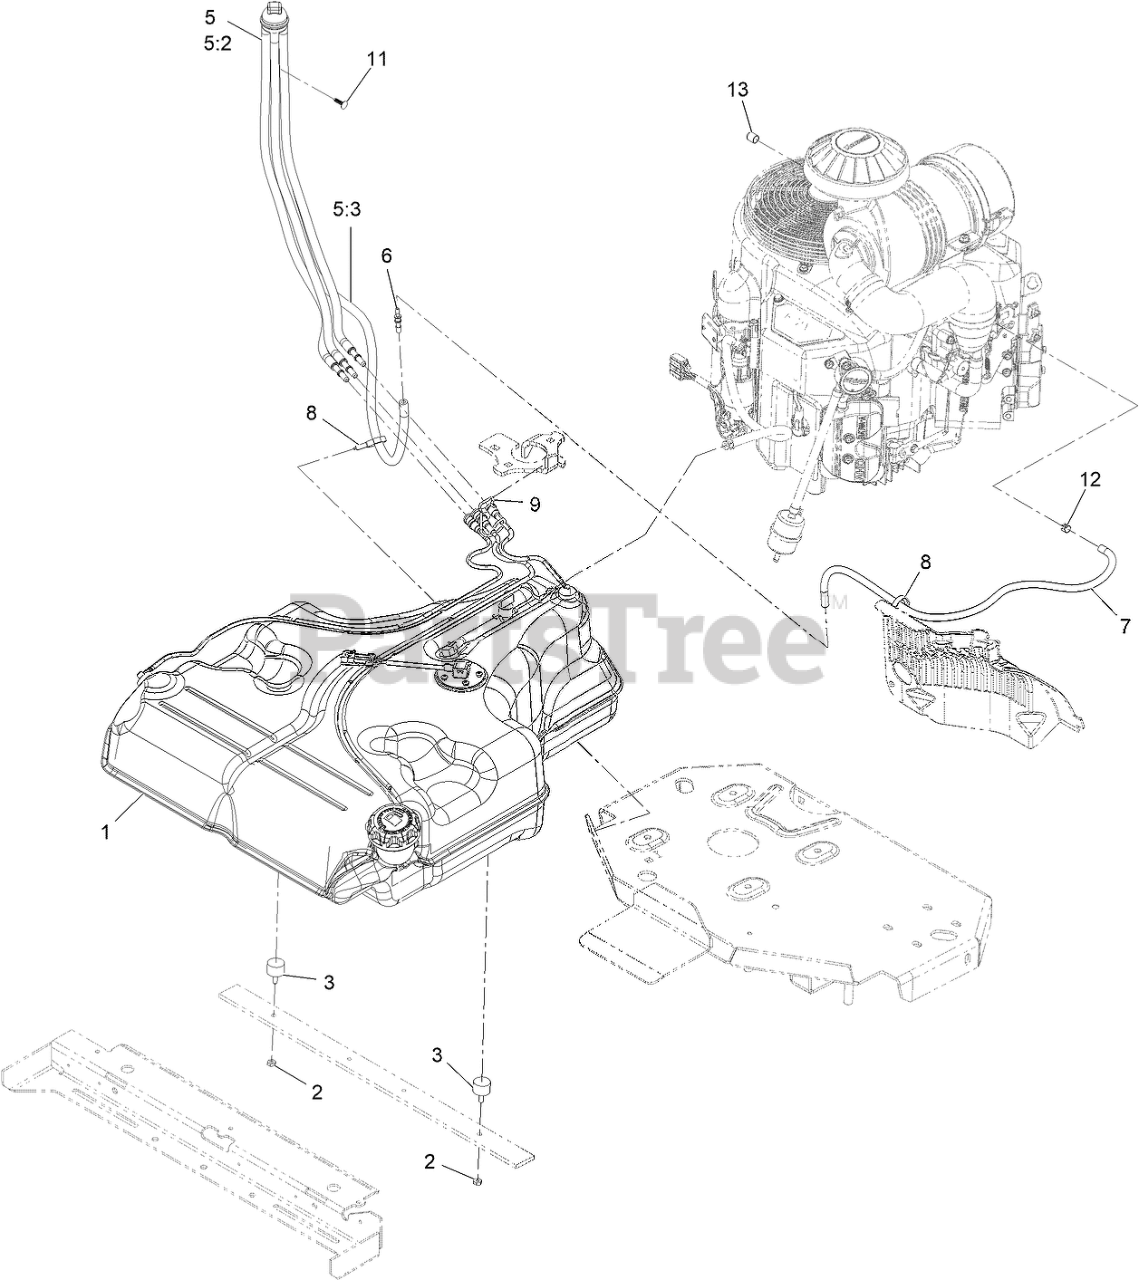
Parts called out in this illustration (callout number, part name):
1	FUEL TANK ASM
2	NUT-JAM
5	FUEL MANIFOLD VENT ASM
5:2	HOSE-FUEL
5:3	HOSE-FUEL
6	BARB-FUEL
7	Hose-Fuel
8	CLAMP-HOSE
9	RETAINER-LINE, VAPOR
11	PLUG-PLASTIC
12	CLAMP-HOSE
13	PLUG-PORT
